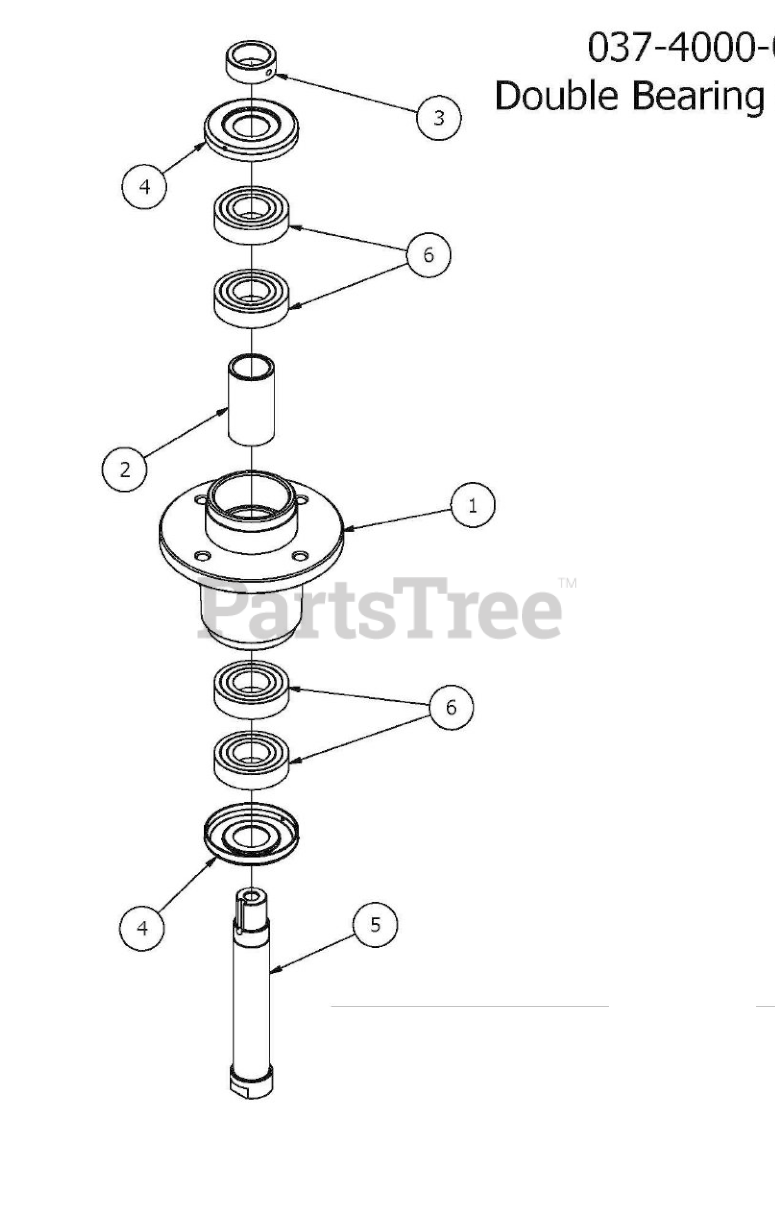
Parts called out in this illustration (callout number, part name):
1	4000 Series Spindle Housing
2	4000 Series Spindle Spacer
3	Locking Collar w/ 1/4"-20 Set Screw
4	Spindle Dust Cap
5	Spindle Shaft
6	Bearing - 6206
